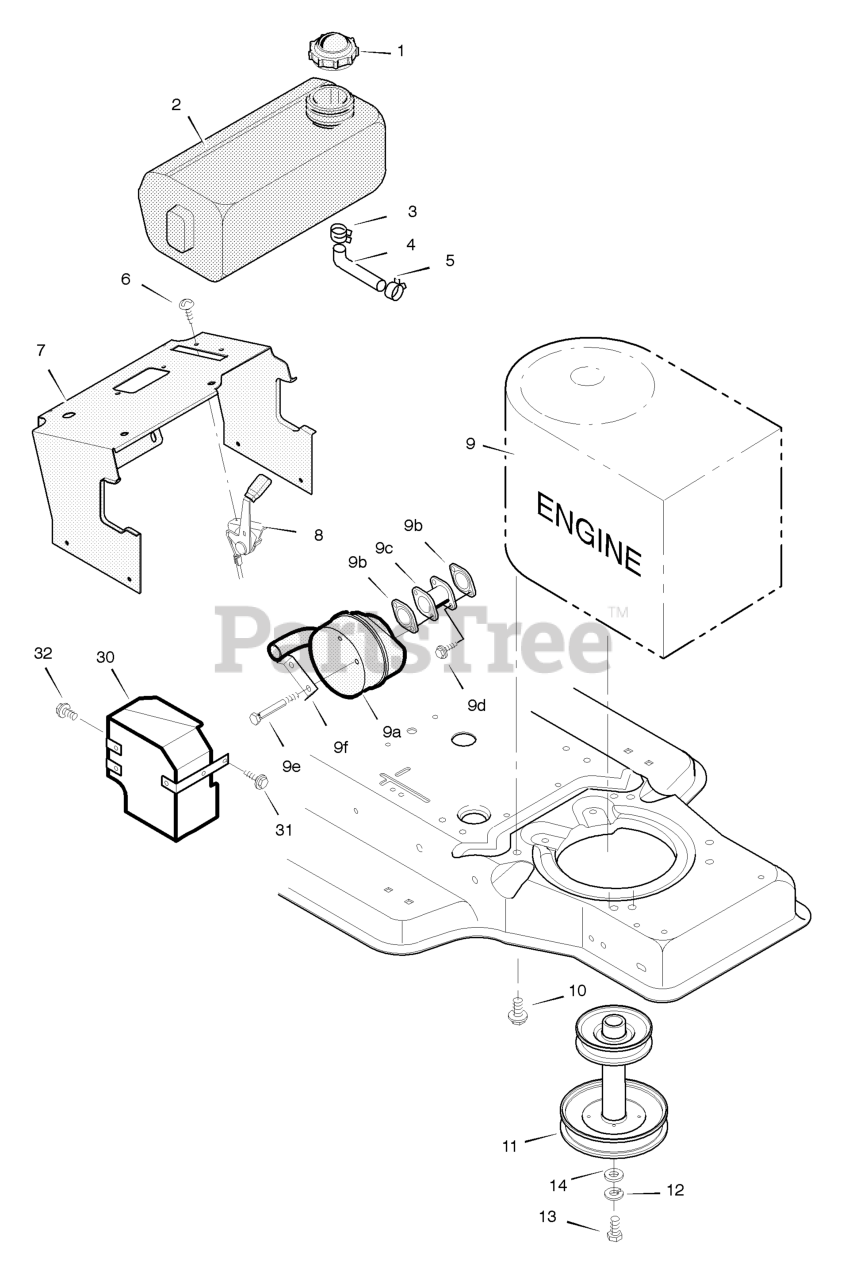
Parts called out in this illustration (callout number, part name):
1	Fuel Cap
2	Fuel Tank
3	Hose Clamp
4	Fuel Line (Must cut to length)
5	Hose Clamp
7	Support, Dash
8	Throttle Control
9	Engine *
9B	GASKET, Exhaust
9C	Adapter, Muffler
9D	Screw, Adapter
9E	Bolt, Muffler
9F	Lock, Screw
10	Bolt, Engine Mount
11	Stack Pulley Assembly
12	Lockwasher
13	Bolt, Hex
30	Shield, Heat
